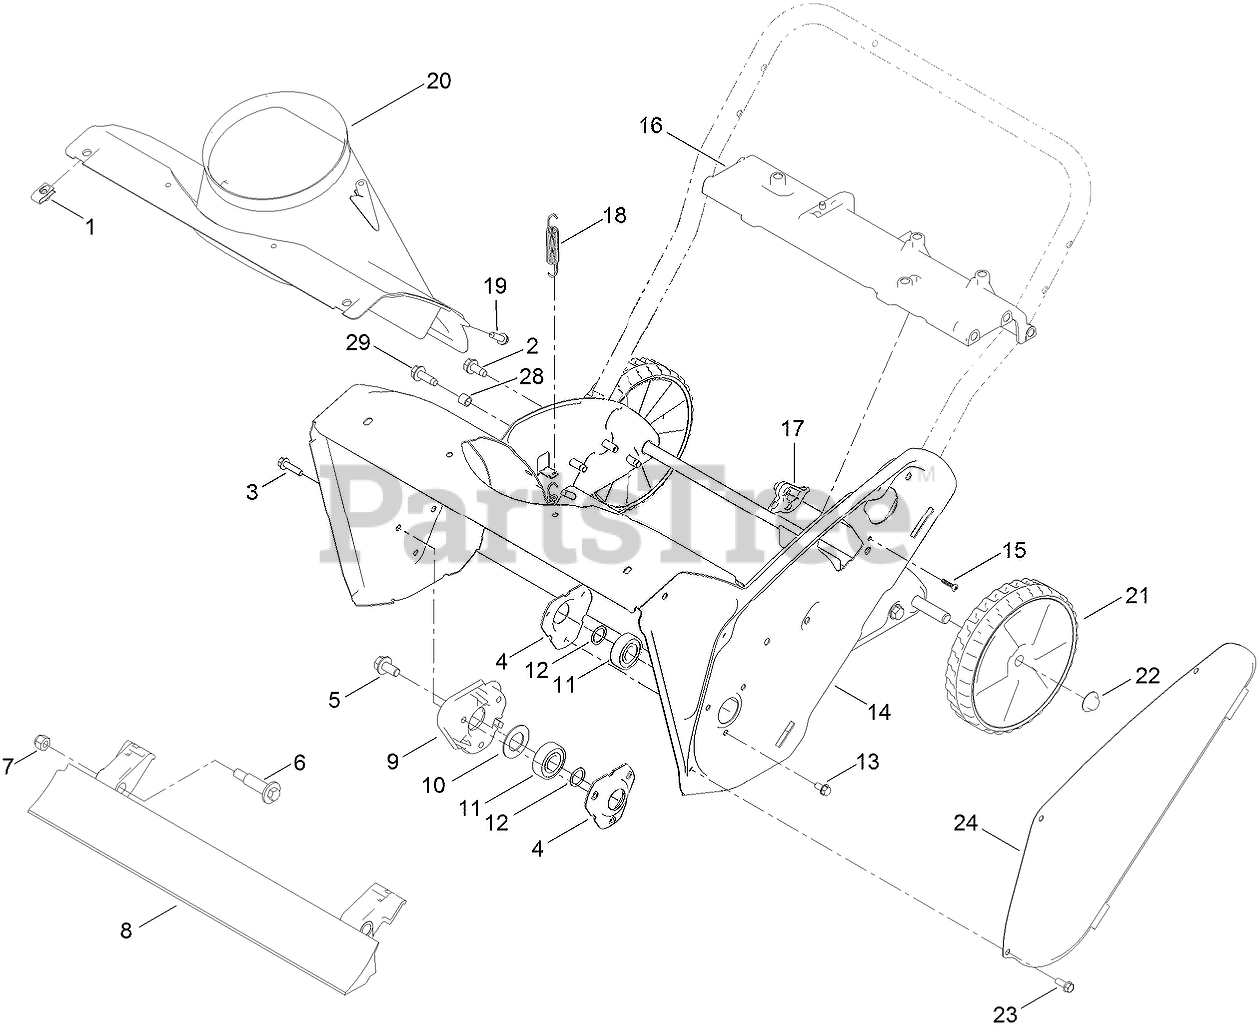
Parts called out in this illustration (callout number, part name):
2	SCREW-THD ROLL, HWH
3	SCREW-HWHTF
4	FLANGE-BEARING
5	SCREW-HWH
6	BOLT-SHOULDER
7	NUT-HEX
8	BLADE-SCRAPER
9	SPACER-BEARING, RH
10	WASHER-RUBBER
12	WASHER-THRUST
13	SCREW-HWH
14	HOUSING-AUGER
15	SCREW-PPH
16	BRACE-FRAME
17	GUIDE-CABLE, CLUTCH
18	SPRING-EXTENSION
19	SCREW-PLASTITE, HWH
20	CHUTE-LOWER
21	WHEEL ASM
22	NUT-PUSH
23	SCREW-HWH
24	COVER-BELT
28	SPACER-GROMMET
29	SCREW-THD ROLL, HWH
